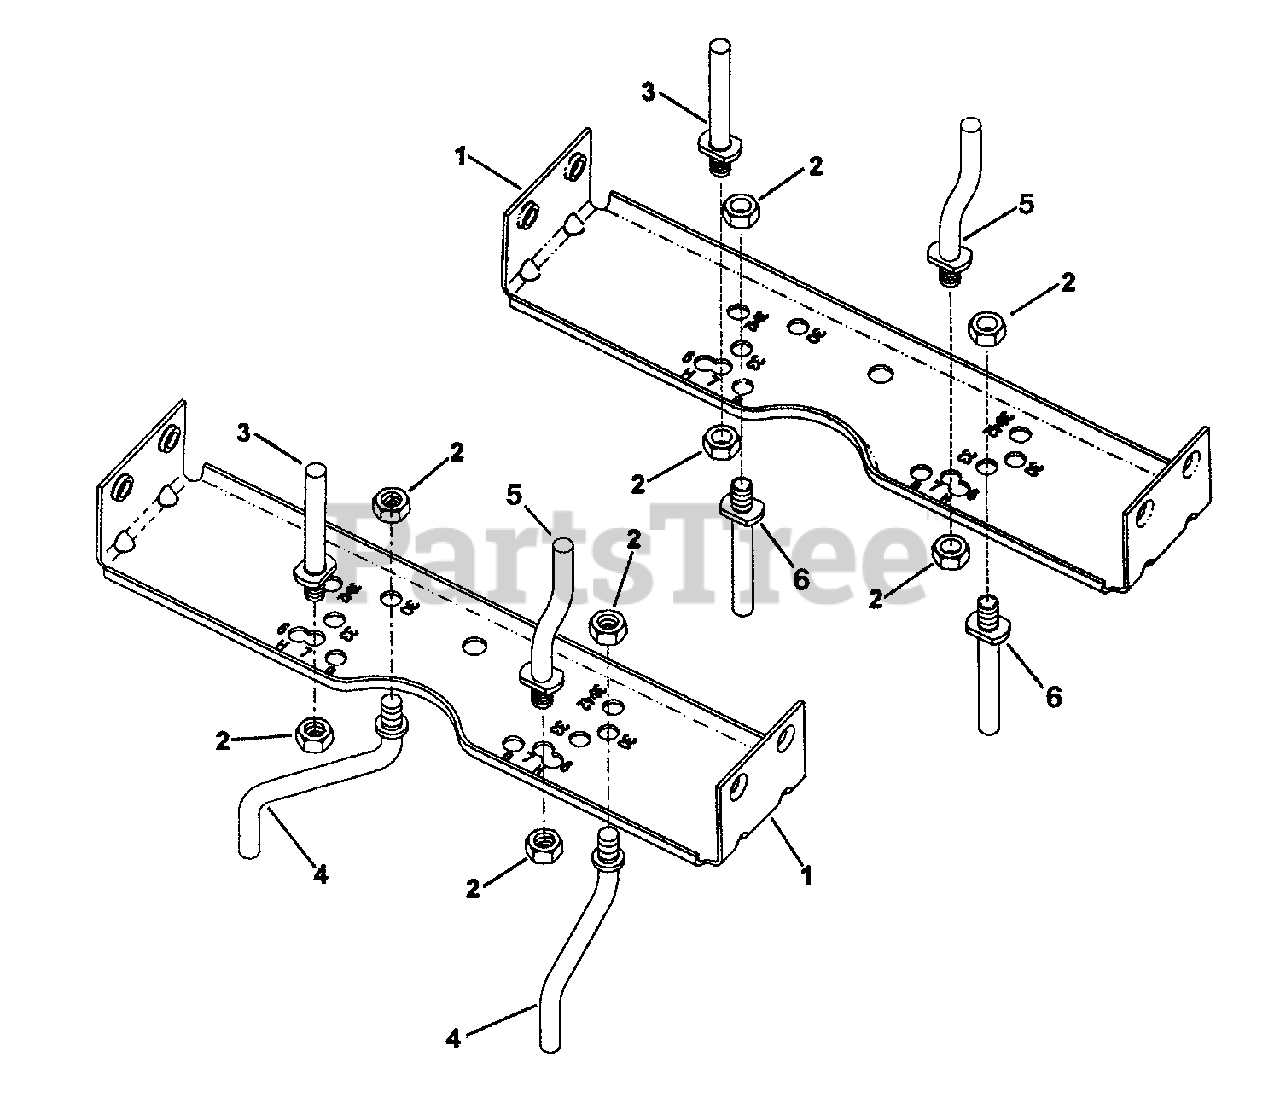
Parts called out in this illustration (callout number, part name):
1	BRACKET, Belt Guide
2	NUT, 5/16-18 Hex Center Lock, GR5 or B
3	STUD, Belt Guide
4	STUD, Belt Guide 38" Dual Brake Deck
5	STUD, Belt Guide
6	STUD, Belt Guide 33" Deck
